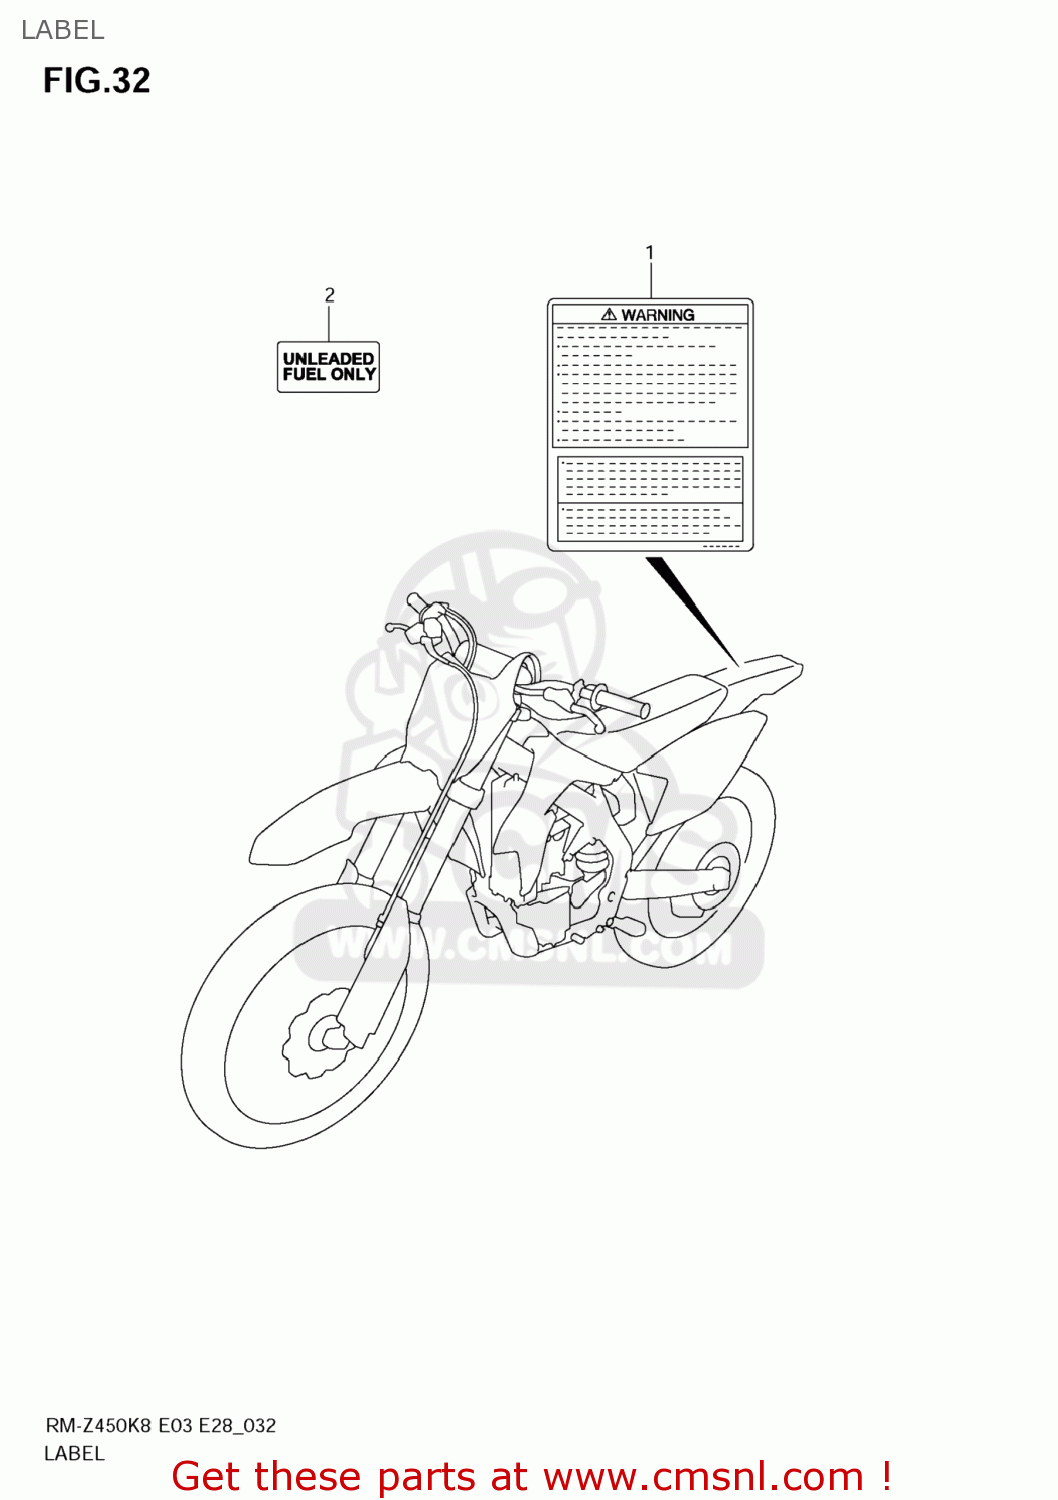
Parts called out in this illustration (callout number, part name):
1	LABEL,WARNING
2	LABEL,UNLEADED FUEL
3	MANUAL,OWNER'S
